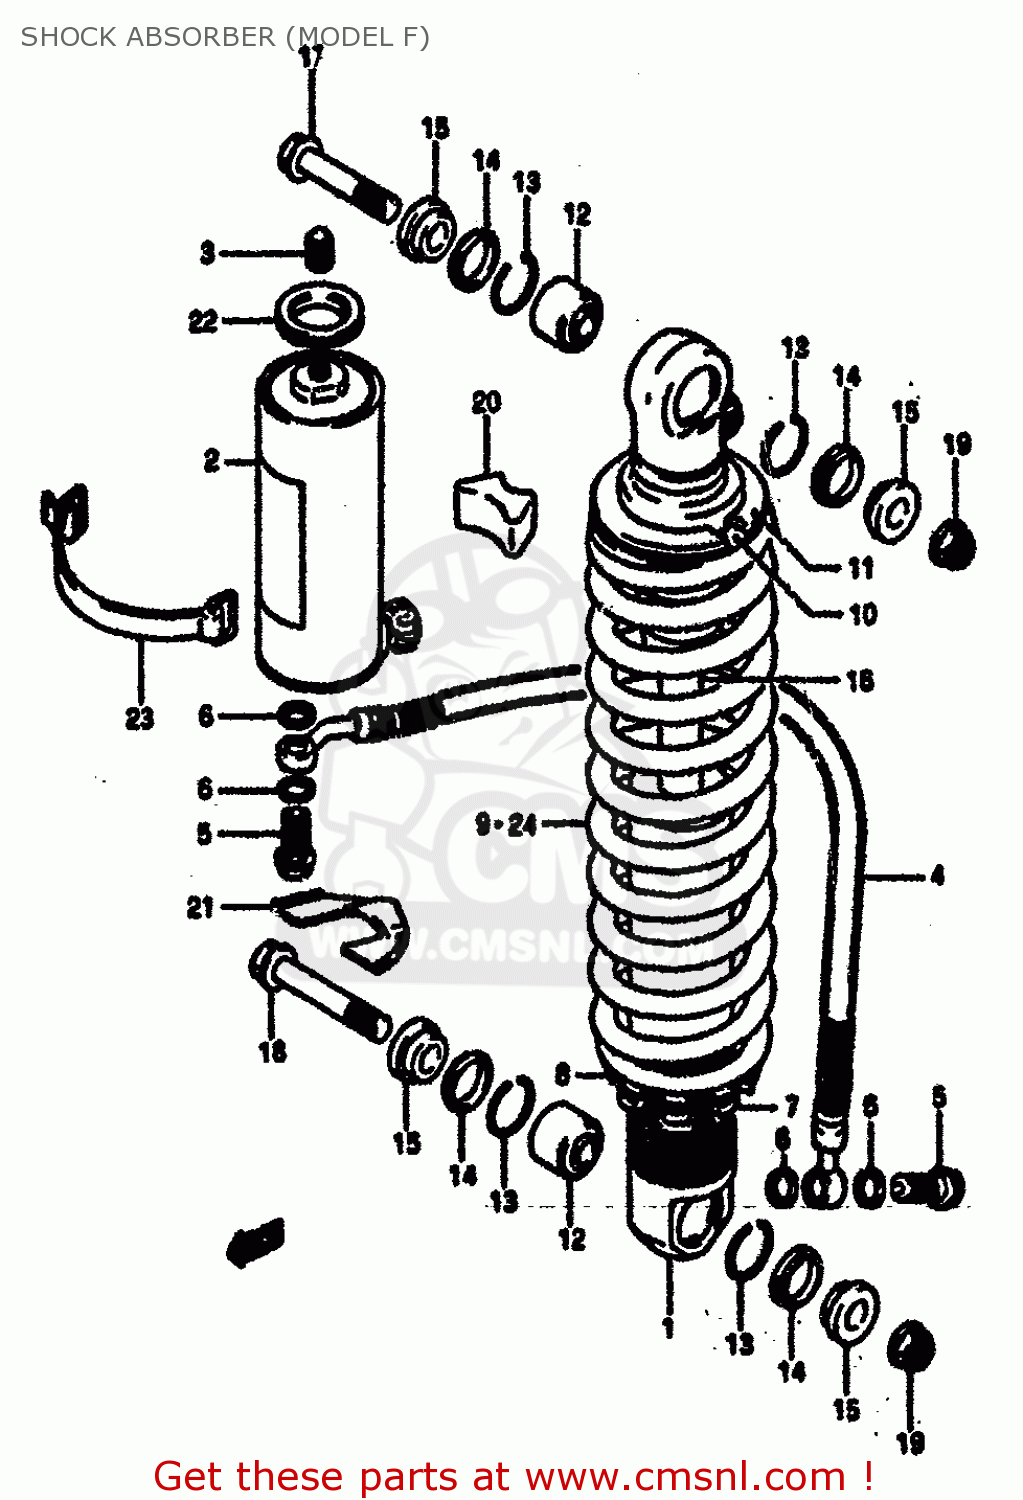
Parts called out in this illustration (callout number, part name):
1	ABSORBER ASSEMBLY,REAR SHOCK
2	RESERVOIR TANK,REAR SHOCK
3	CAP
4	HOSE,REAR SHOCK ABSORBER
5	BOLT,REAR SHOCK ABSORBER
6	GASKET (NAS)
7	GUIDE,REAR SHOCK ABSORBER SPRING
8	GUIDE,SPRING
9	SPRING
10	WASHER
11	GUIDE,SPRING
12	BEARING,REAR SHOCK ABSORBER
13	RING
14	SEAL,DUST RR SHOCK ABSORBER
15	COLLAR
16	ROD,PISTON
17	BOLT,REAR SHOCK ABSORBER
18	BOLT(10X52)
19	NUT
20	CUSHION,RESERVOIR TANK
21	CUSHION,RESERVOIR TANK
22	CUSHION,RESERVOIR TANK
23	BAND
24	SPRING
